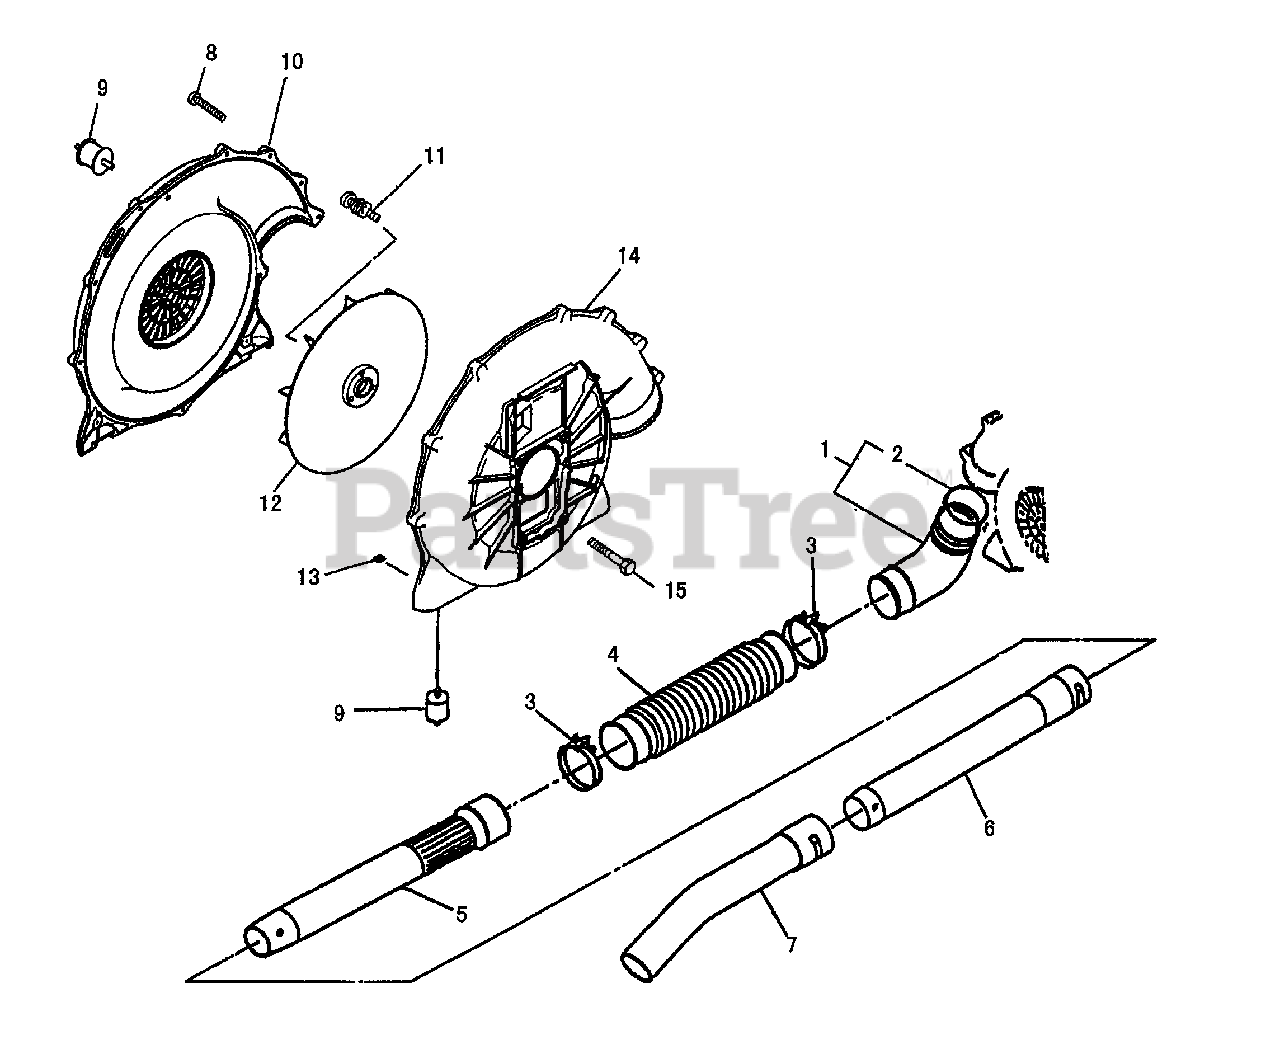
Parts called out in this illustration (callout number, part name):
1	Elbow Pipe
2	O-Ring
3	Hose Band
4	Flex Pipe
5	Base Pipe
6	Middle Pipe
7	Bend Pipe
8	Tapping Screw (M5x30)
9	Anti-Vibe Mount
11	Pre-Coat Lock Bolt
13	Hex Nut
15	Pre-Coat Lock Bolt
